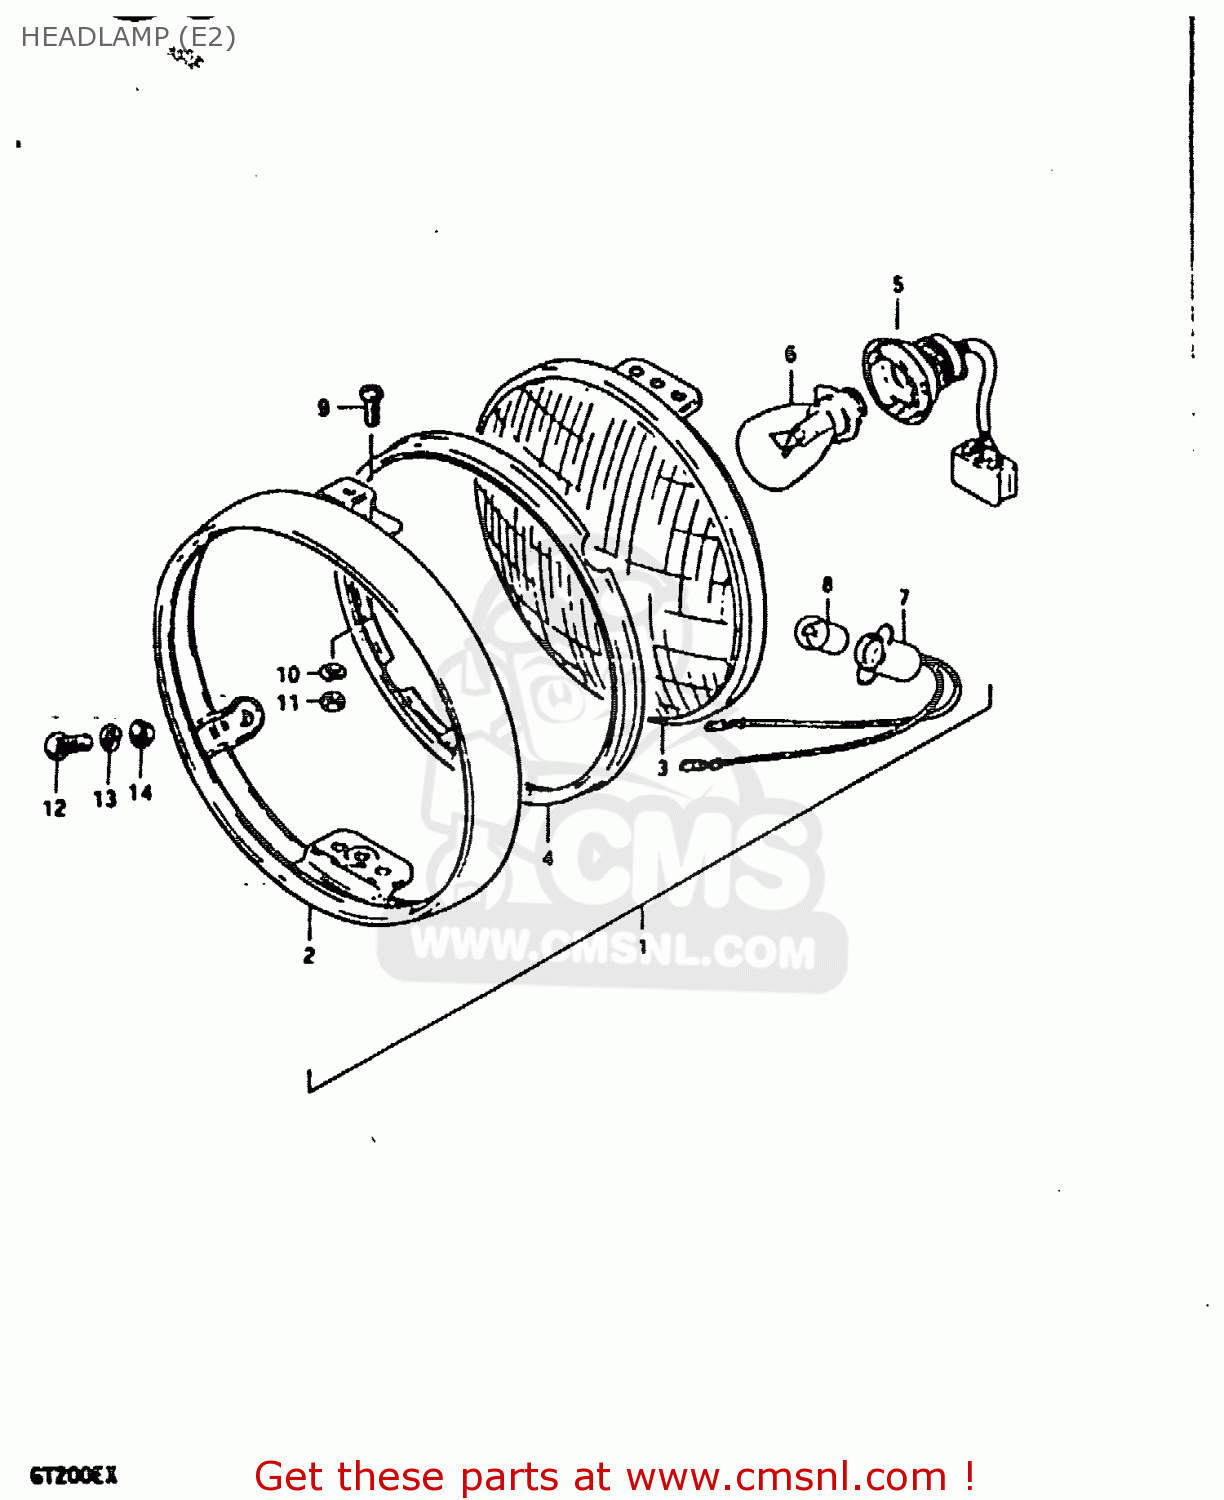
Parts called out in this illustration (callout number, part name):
1	HEADLAMP ASSY
2	RIM
3	UNIT, HEAD LIGHT
4	RETAINER,HEADLAMP
5	SOCKET
6	BULB 12V35/35W
7	SOCKET
8	BULB(12V3.4W,STANLEY,A72A)
9	SCREW
10	LOCK WASHER
11	NUT
12	SCREW
13	WASHER,LOCK
14	WASHER
